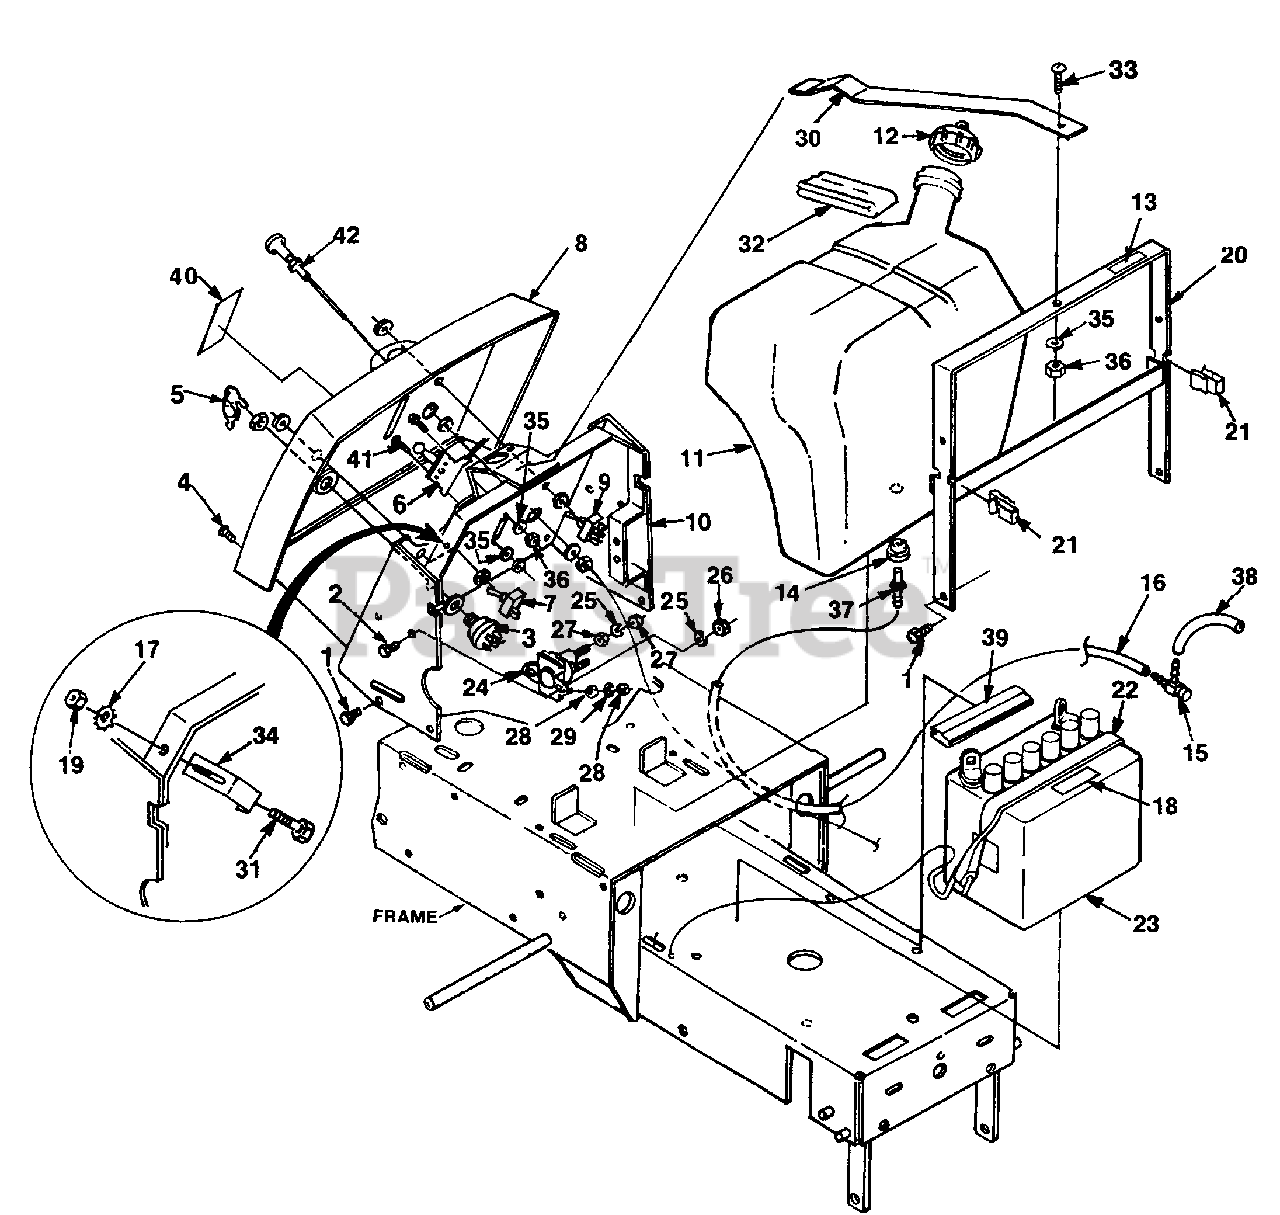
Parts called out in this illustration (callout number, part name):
1	BOLT- 1/4-14 x .44
2	SCREW- 1/4-20 x 1/2 hex
3	SWITCH- Key
4	SCREW- #10 x 3/4
6	CONTROL (12HP)
8	PANEL- Dash (12HP)
9	SWITCH- PTO
10	CONTROL TOWER ASSY
11	TANK- Gas
12	CAP- Fuel
13	DECAL- Gasohol
15	VALVE- Needle
16	TUBING- Rubber (YT-12)
17	WASHER- 5/16
18	DECAL- Battery
19	NUT- 5/16-18
22	STRAP- Hold down
23	BATTERY (12HP)
25	WASHER- Lock 1/4
26	NUT- Hex 1/4-20
27	NUT- 1/4-20
28	NUT- Hex 8-32
29	WASHER- Lock #8
30	STRAP- Upper PTO
31	SCREW- 5/16-18 x 5/8
32	PAD- Rubber
33	SCREW- #10-24 x 1/2
34	BRACKET- Gas Tank
36	NUT- Hex Lock 10-24
37	FITTING- Gas Tank
38	TUBING- Rubber
39	CUSHION- Rubber
40	DECAL- Throttle (12HP)
41	SCREW- #10-24 x 3/8
42	CONTROL- Choke
